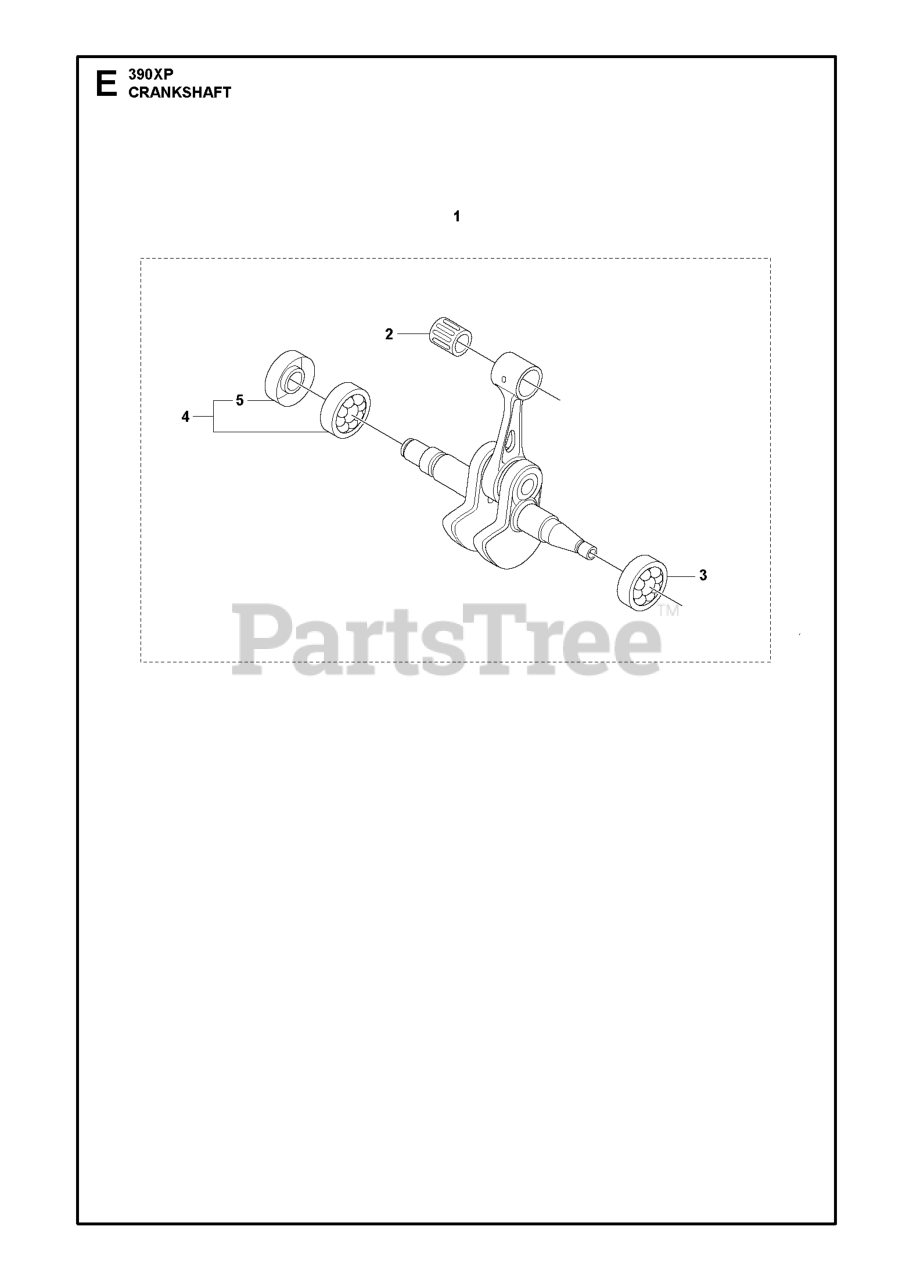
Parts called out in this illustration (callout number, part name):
1	Crankshafts
2	SUPPORT BUSHING
3	BALL BEARING 6203 C3
4	BALL BEARING
5	SEALING RING
